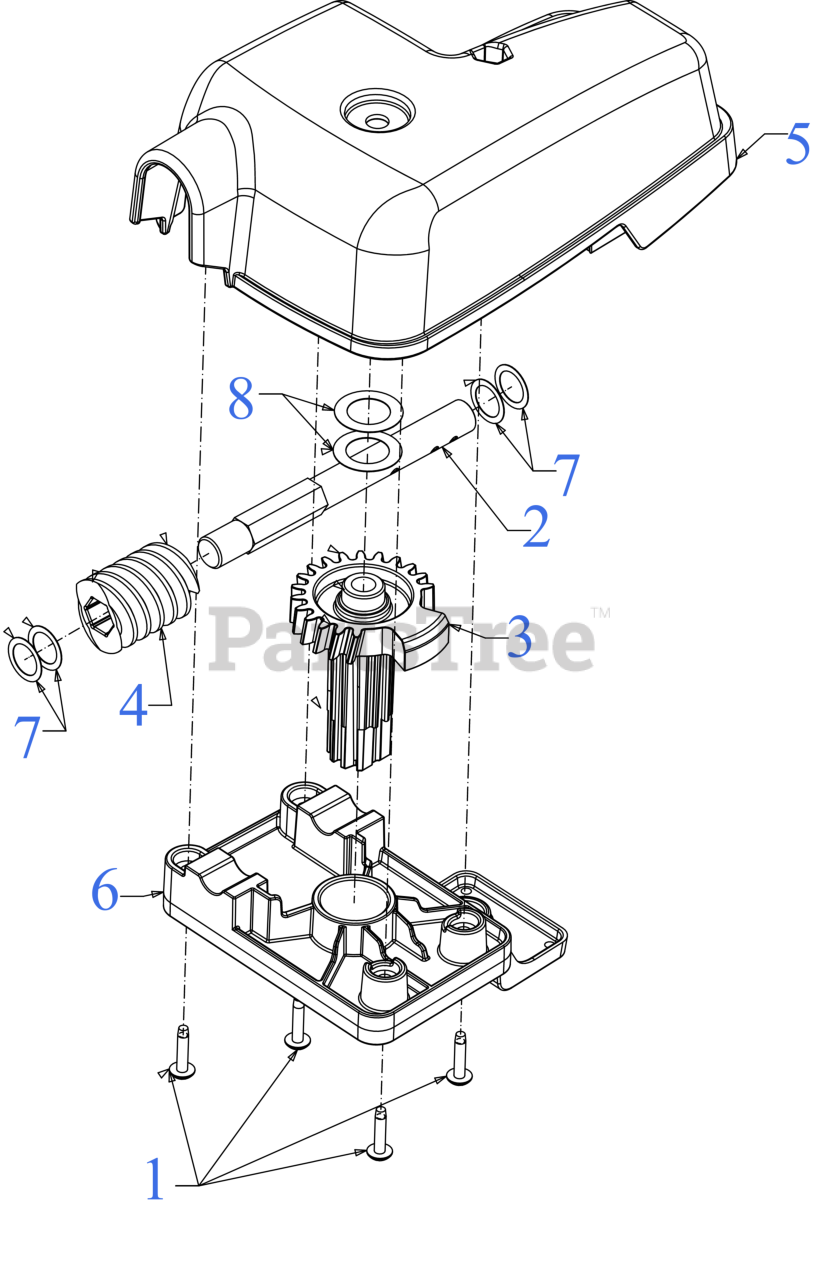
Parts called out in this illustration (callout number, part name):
1	SCREW 8-16 x 3/4
2	HEX SHAFT
3	GEAR-HELICAL 23T
4	NYLON WORM- W/HEX CORE
5	CHUTE CONTROL GEAR COVER (2WAY)
6	CHUTE HOUSING GEAR BASE
7	FLAT WASHER .504 X.700X.010
8	SHIM WASHER .632X1.000X.010:HD
